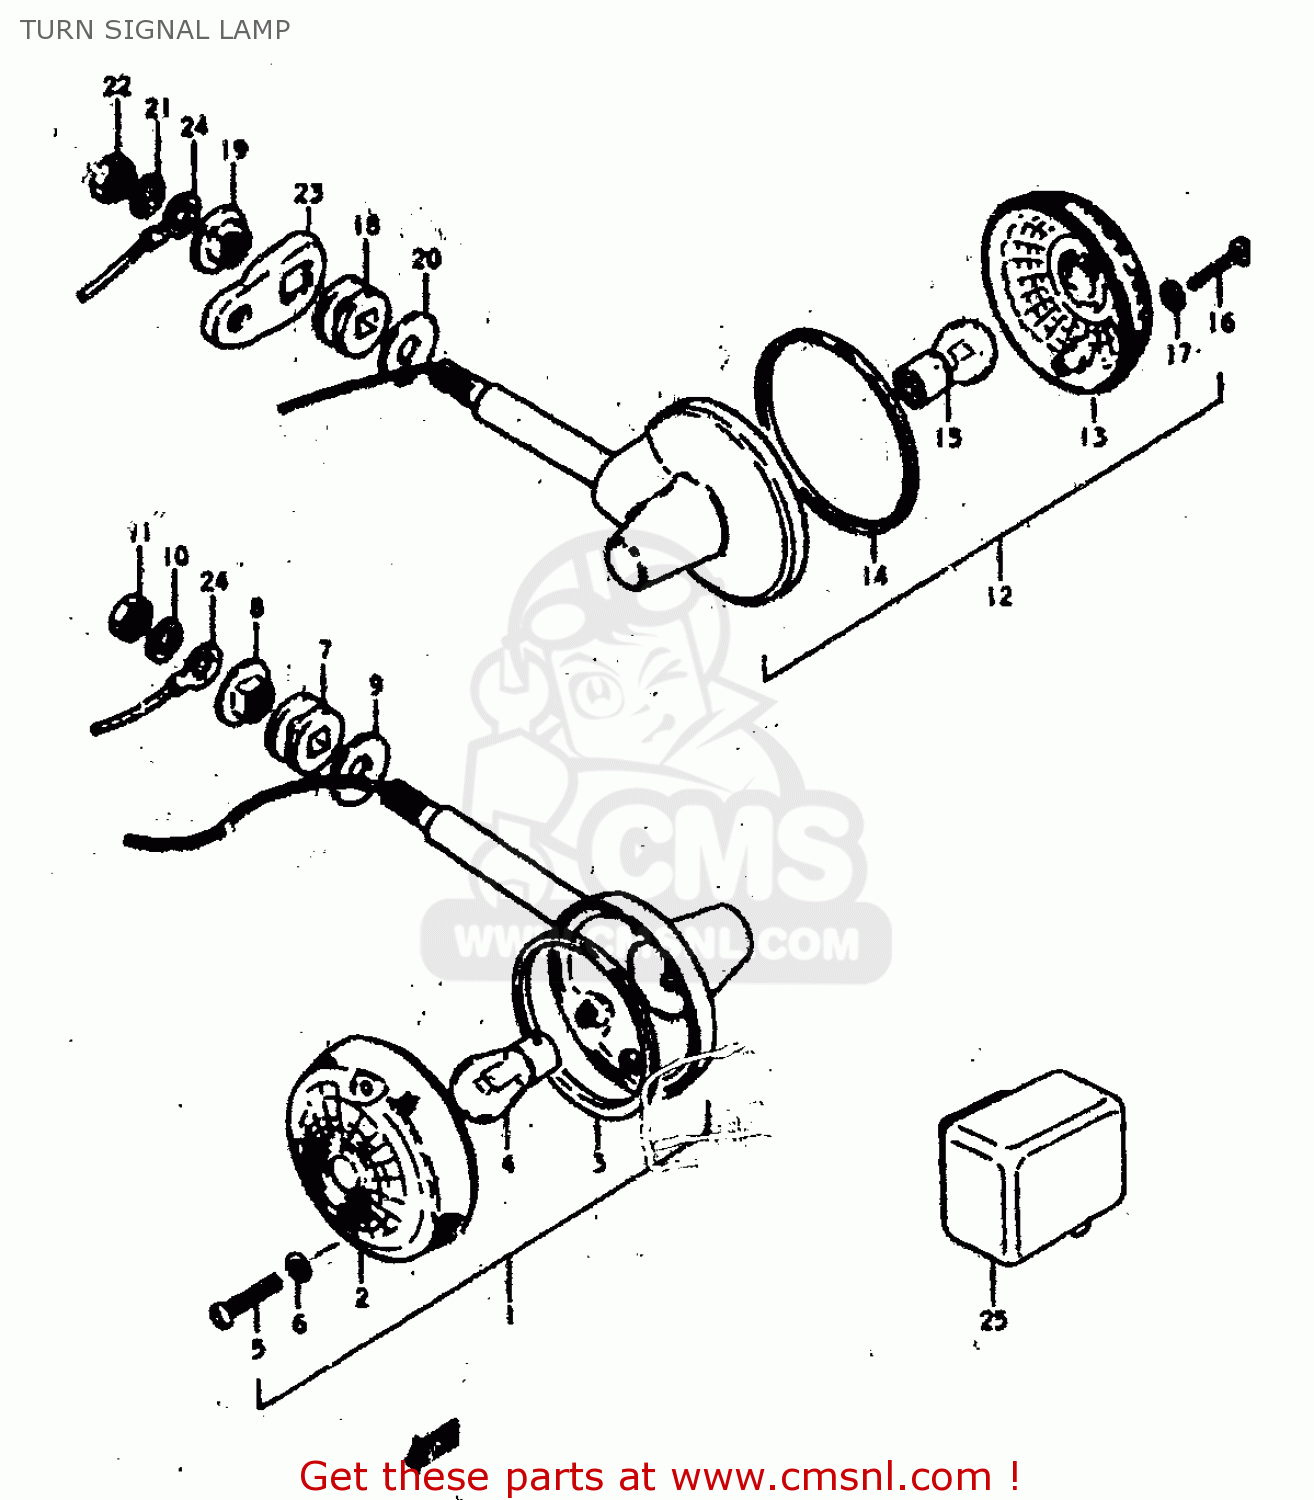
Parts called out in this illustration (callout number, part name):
1	LAMP ASSEMBLY,FRONT TURN SIGNAL
2	LENS
3	GASKET (NAS)
4	BULB(12V23W,STANLEY,A4577A)
5	SCREW
6	GASKET (NAS)
7	CUSHION
8	SPACER,RR TURNSIGNAL LAMP
9	WASHER
10	LOCK WASHER
11	NUT
12	LAMP ASSEMBLY,REAR TURN SIGNAL
13	LENS
14	GASKET (NAS)
15	BULB(12V23W,STANLEY,A4577A)
16	SCREW
17	GASKET (NAS)
18	CUSHION
19	SPACER,RR TURNSIGNAL LAMP
20	WASHER
21	LOCK WASHER
22	NUT
23	BRACKET,TURN SIGNAL
24	WIRE
25	RELAY,TURN SIGNAL
